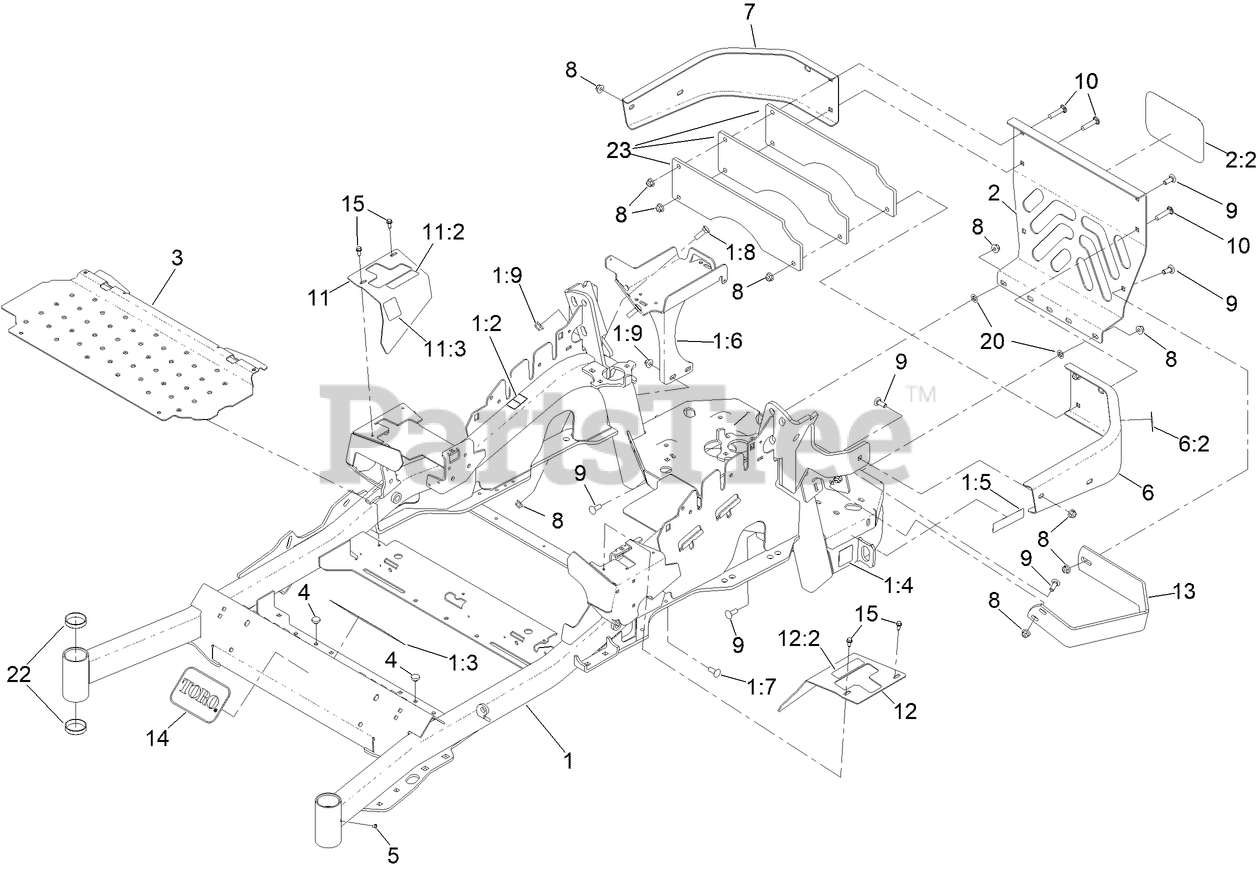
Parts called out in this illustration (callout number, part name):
1	MAINFRAME SERVICE ASM - RD
1:2	DECAL-WARNING
1:3	DECAL-DANGER
1:4	DECAL-HAZARD, PINCHED FINGER
1:5	DECAL-ARRESTOR, SPARK
1:6	BATTERY MOUNT ASM
1:7	SCREW-CARR
1:8	BOLT-CARR
1:9	NUT-HF, NI
2	REAR GUARD ASM
2:2	DECAL
3	FLOORPAN
4	BUMPER
6	LH BUMPER ASM
6:2	DECAL-WARNING
7	BUMPER-RH
8	NUT-HF, NI
9	SCREW-CARR
10	SCREW-CARR
11	RH MOTION CONTROL COVER ASM
11:2	DECAL-CONTROL, MOTION
11:3	DECAL-PARK BRAKE, CE
12	LH MOTION CONTROL COVER ASM
12:2	DECAL-CONTROL, MOTION
13	GUARD-MUFFLER
14	DECAL
15	SCREW-HWH
20	NUT-PUSH
22	CUP-BEARING
23	PLATE-WEIGHT, 6 LB
